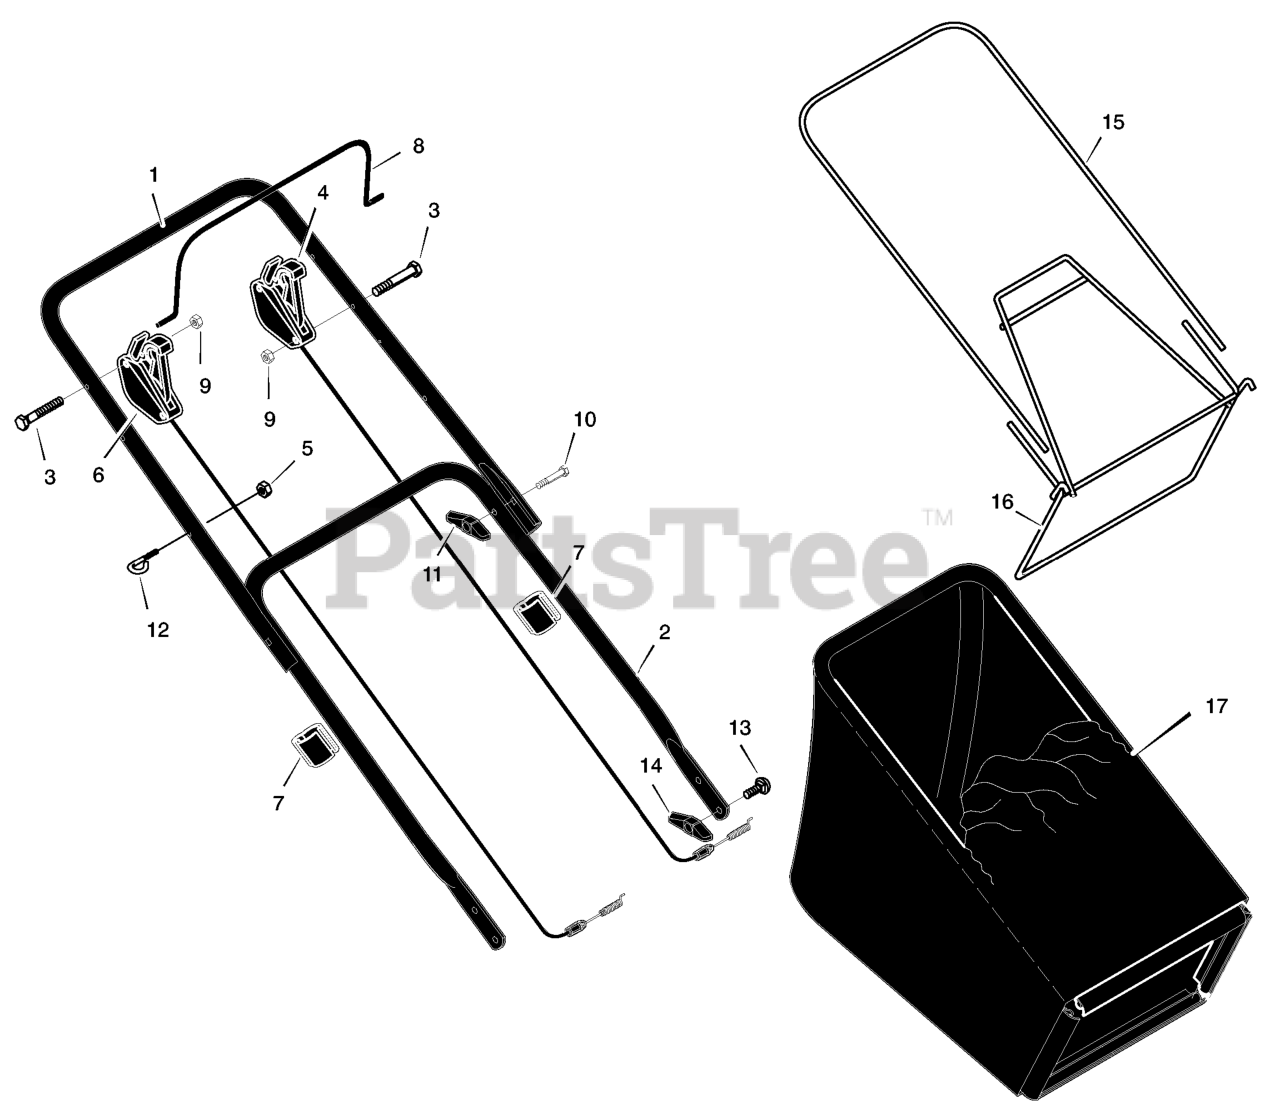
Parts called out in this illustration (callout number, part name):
1	Handle, Upper
2	Handle, Lower
4	Control, Drive
5	Locknut
6	Control, Starter
7	Fastener, Cable
8	Lever, Stop
11	Knob
12	Guide, Rope
13	Bolt, Carriage
14	Knob, Plastic
15	Tube, Bag
16	Frame Assembly
17	Bag, Cloth
